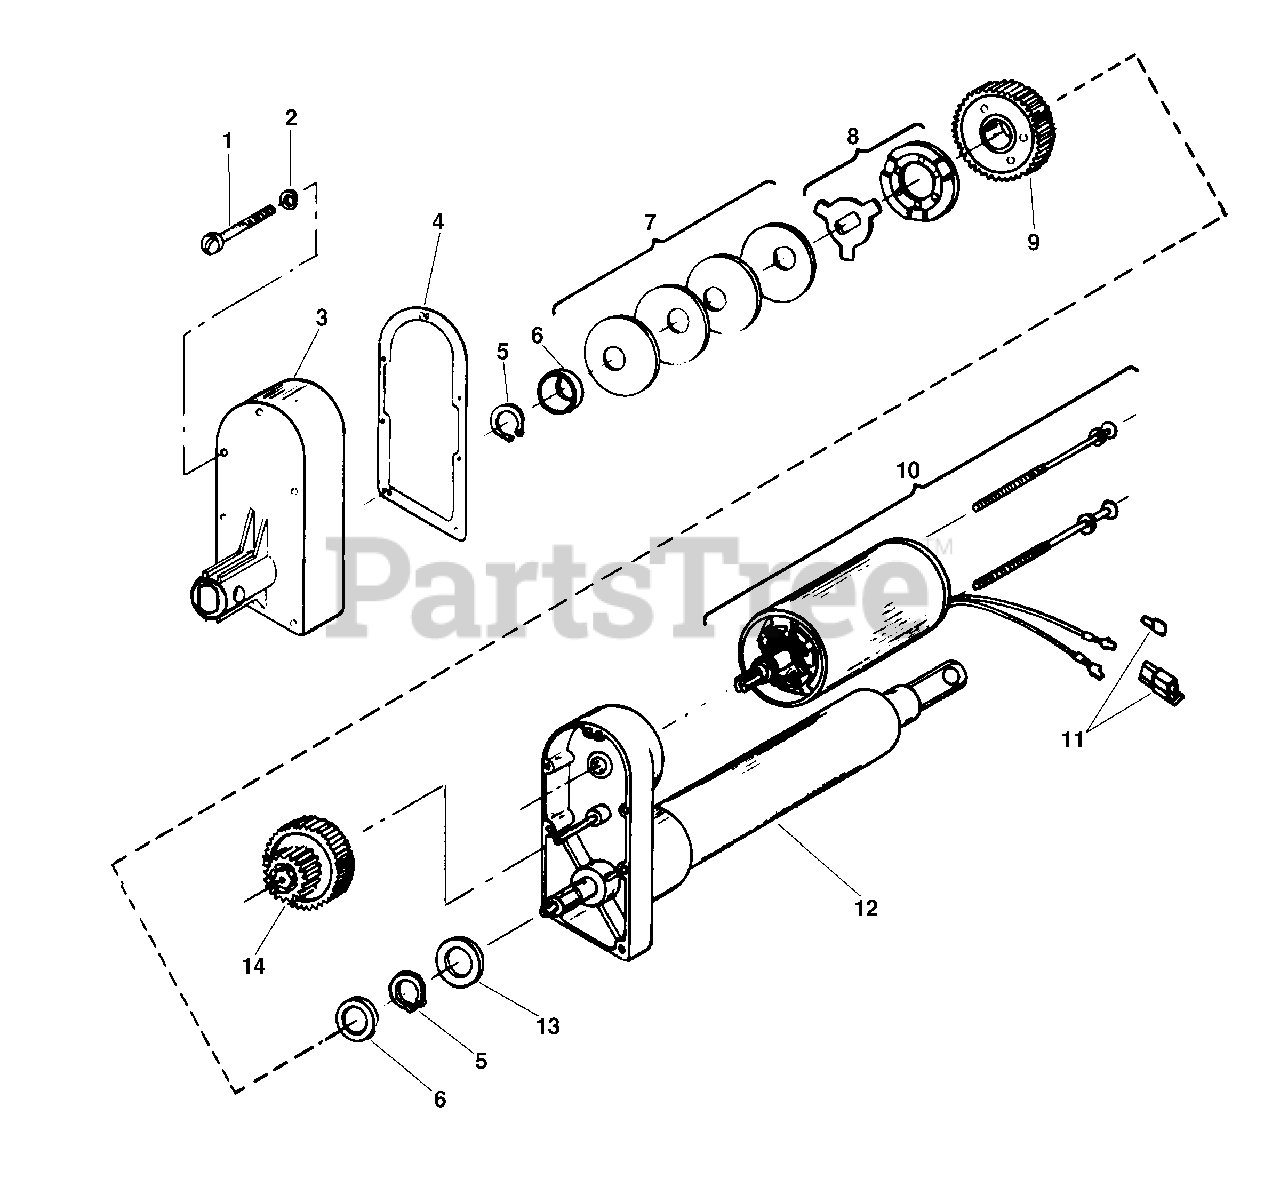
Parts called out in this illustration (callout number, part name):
1	Screw - Sl. Fil. Hd. Mach. No. 10-32 x 1-5/8
2	Lockwasher - No. 10
3	Housing Cover
4	Cover Gasket
5	Snap Ring
6	Retaining Ring
7	Spring Washer
8	Pawl & Ramp Washer
9	Out put Gear
10	Motor - 12V
11	Connector Body Kit
13	Thrust Washer
14	Intermediate Gear
